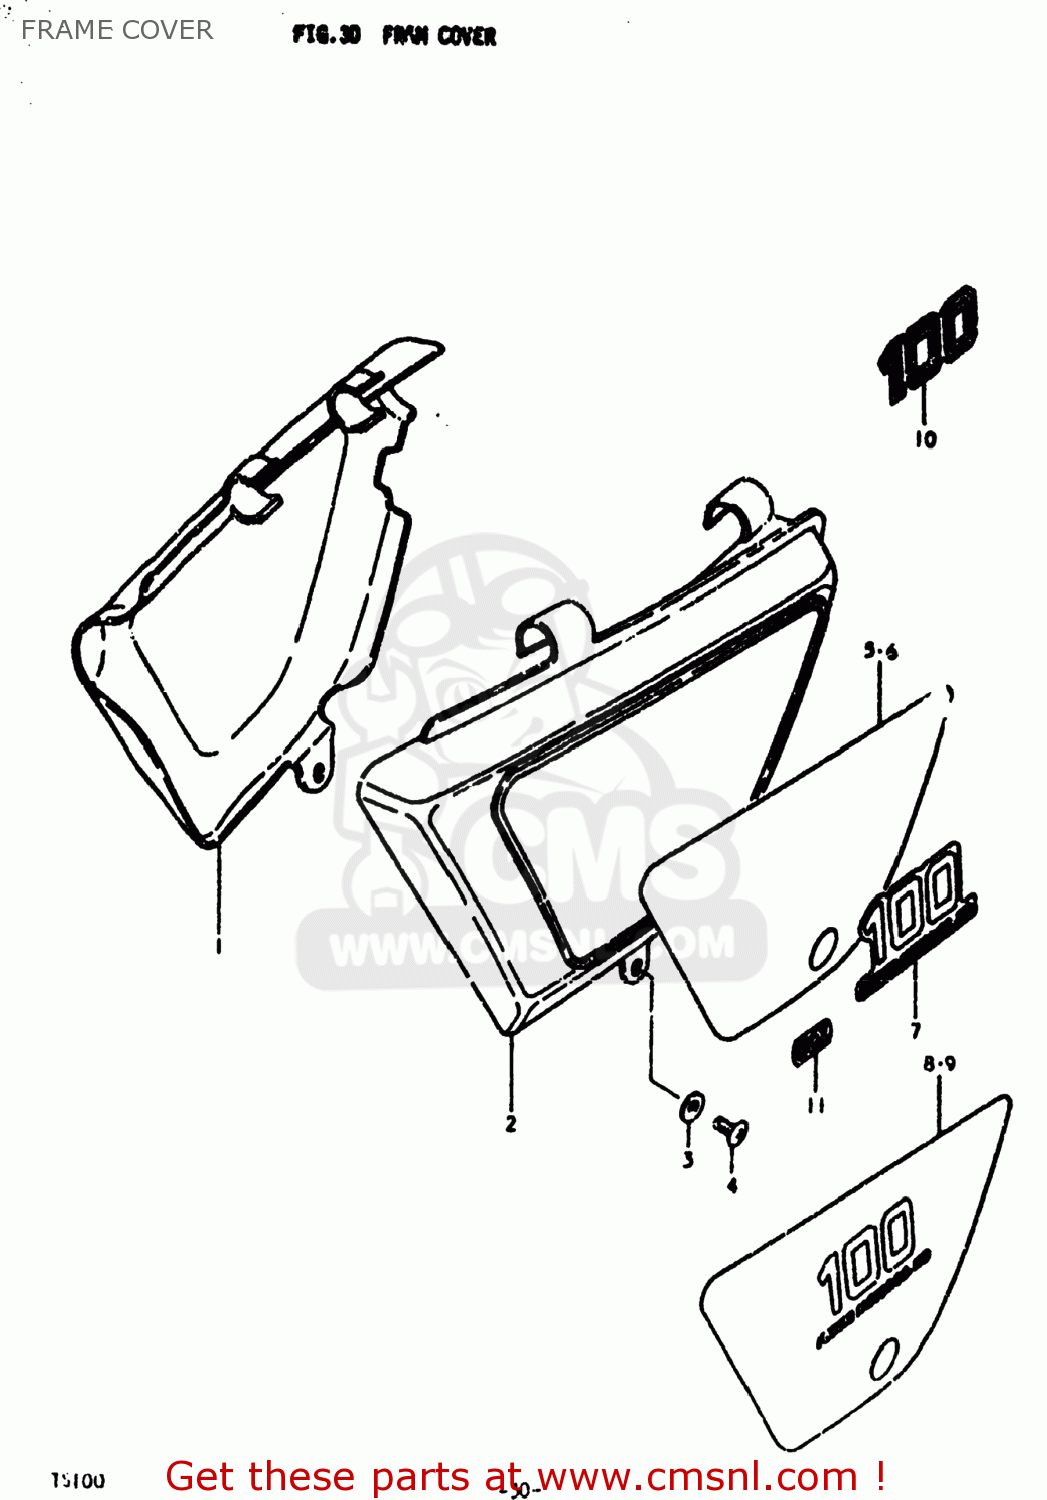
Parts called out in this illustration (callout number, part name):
1	COVER,FRAME,RIGHT
2	COVER,FRAME,LEFT
3	WASHER
4	SCREW 6X12
5	EMBLEM,FRAME COVER
6	EMBLEM,FRAME COVER
7	EMBLEM
8	EMBLEM
9	EMBLEM,FRAME COVER
10	EMBLEM
